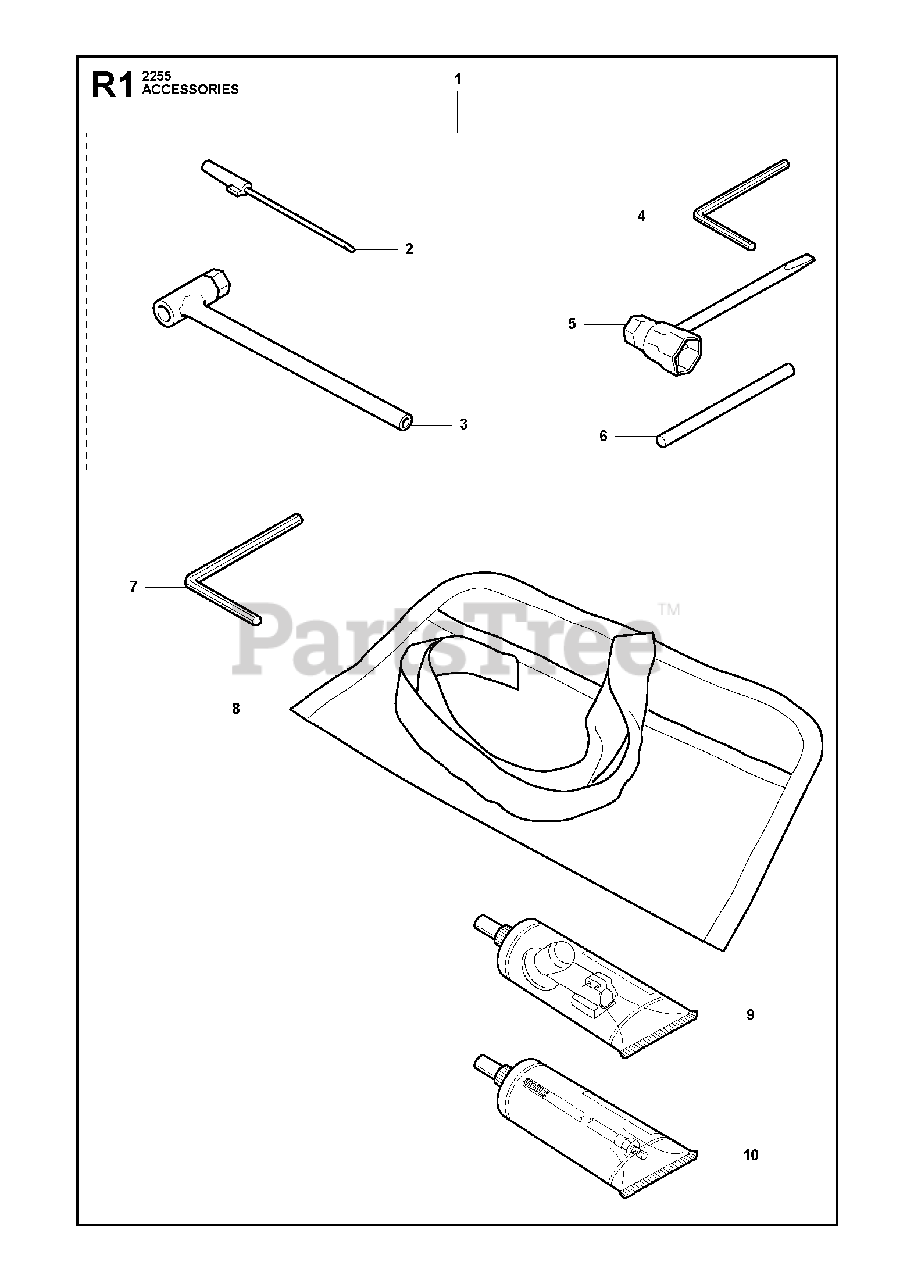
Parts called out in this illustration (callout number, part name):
1	RP ACCESSORY BAG
2	SCREWDRIVER
3	SCRENCH
4	L-KEY WRENCH
5	COMBI TOOL
6	LOCKING PIN
7	KEY
9	BEVEL GEAR GREASE
